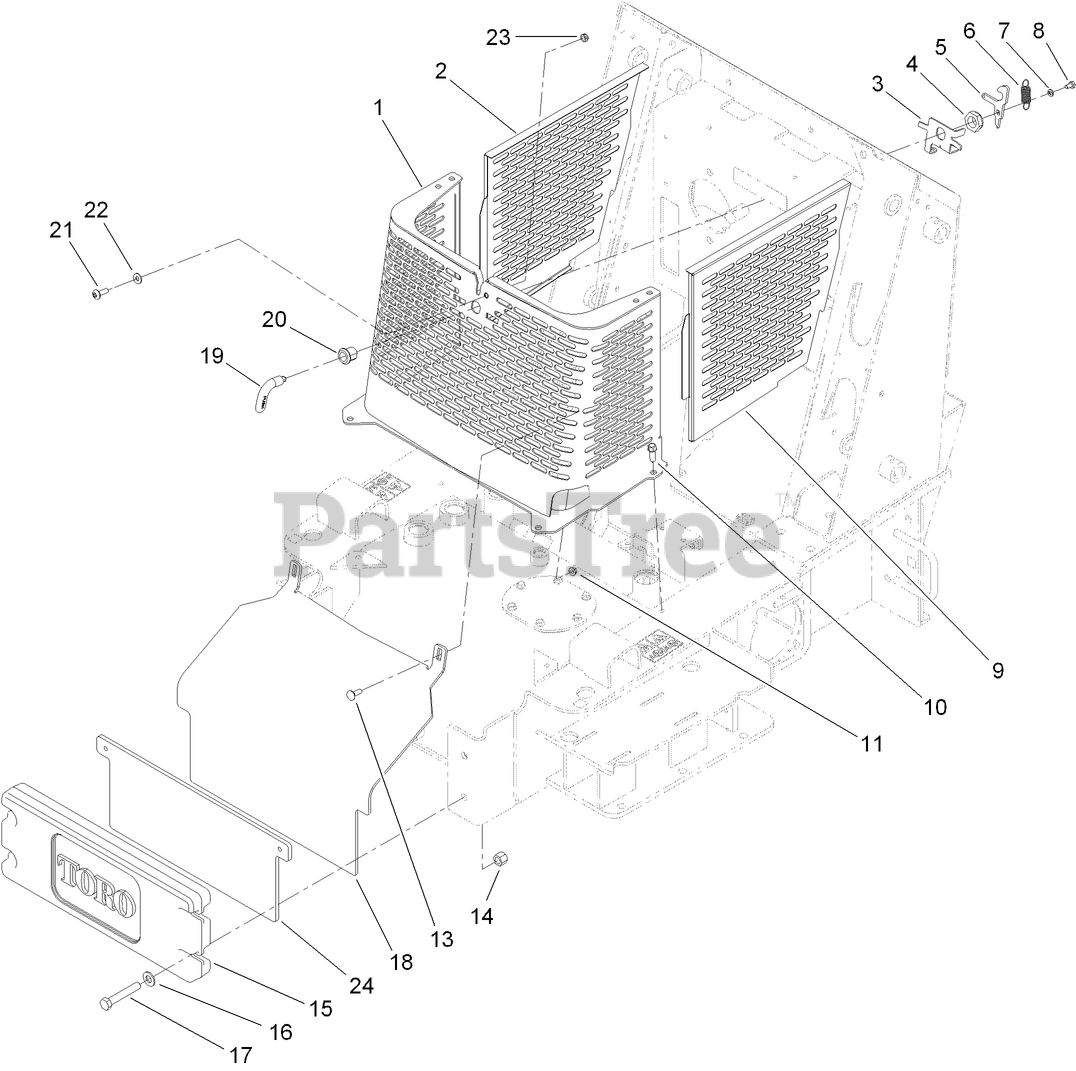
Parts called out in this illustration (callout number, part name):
2	PANEL-SIDE, RH
3	BRACKET-LATCH
4	NUT-LOCK, NI
5	CAM-LATCH
6	SPRING
7	WASHER-LOCK
8	SCREW-HH
9	PANEL-SIDE, LH
10	SCREW-TAPTITE
11	NUT-HF
13	SCREW-CARR
14	NUT-LOCK, NI
15	COUNTERWEIGHT-FRONT
16	WASHER-FLAT
17	SCREW-HH
18	PLATE-FRONT
19	HANDLE-LATCH
20	HOUSING-LATCH
21	SCREW-PTH
22	WASHER-FLAT
23	NUT-LOCK, NI
24	PLATE-COUNTERWEIGHT
